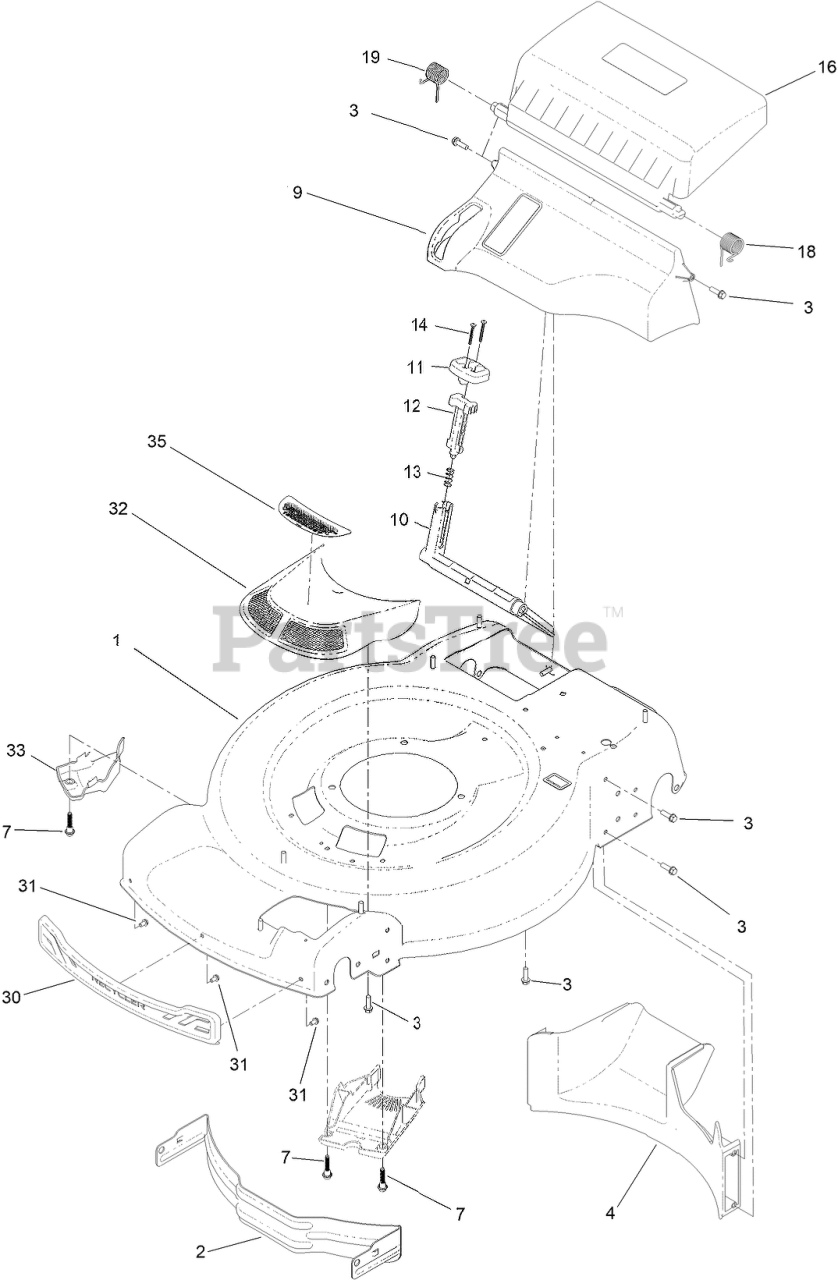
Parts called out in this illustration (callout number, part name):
1	HOUSING ASM
2	BAFFLE-FRONT
3	SCREW-HWH
4	BAFFLE-REAR, RWD
7	SCREW-SHOULDER, HHF
9	ASM-CHUTE, IN MOLD
10	DEFLECTOR-RECYCLE
11	KNOB-RECYCLE
12	LATCH-RECYCLE
13	SPRING-COMPRESSION
14	SCREW-PPH
16	ASM-REAR DOOR, IN-MOLD (60V)
18	SPRING-TORSION, LH
19	SPRING-TORSION, RH
30	BUMPER-FRONT
31	SCREW-PLASTIC, HWH
32	ASM-INTAKE, RWD
33	COVER-INTAKE, BOTTOM
35	DECAL-60V VORTEX TECHNOLOGY
